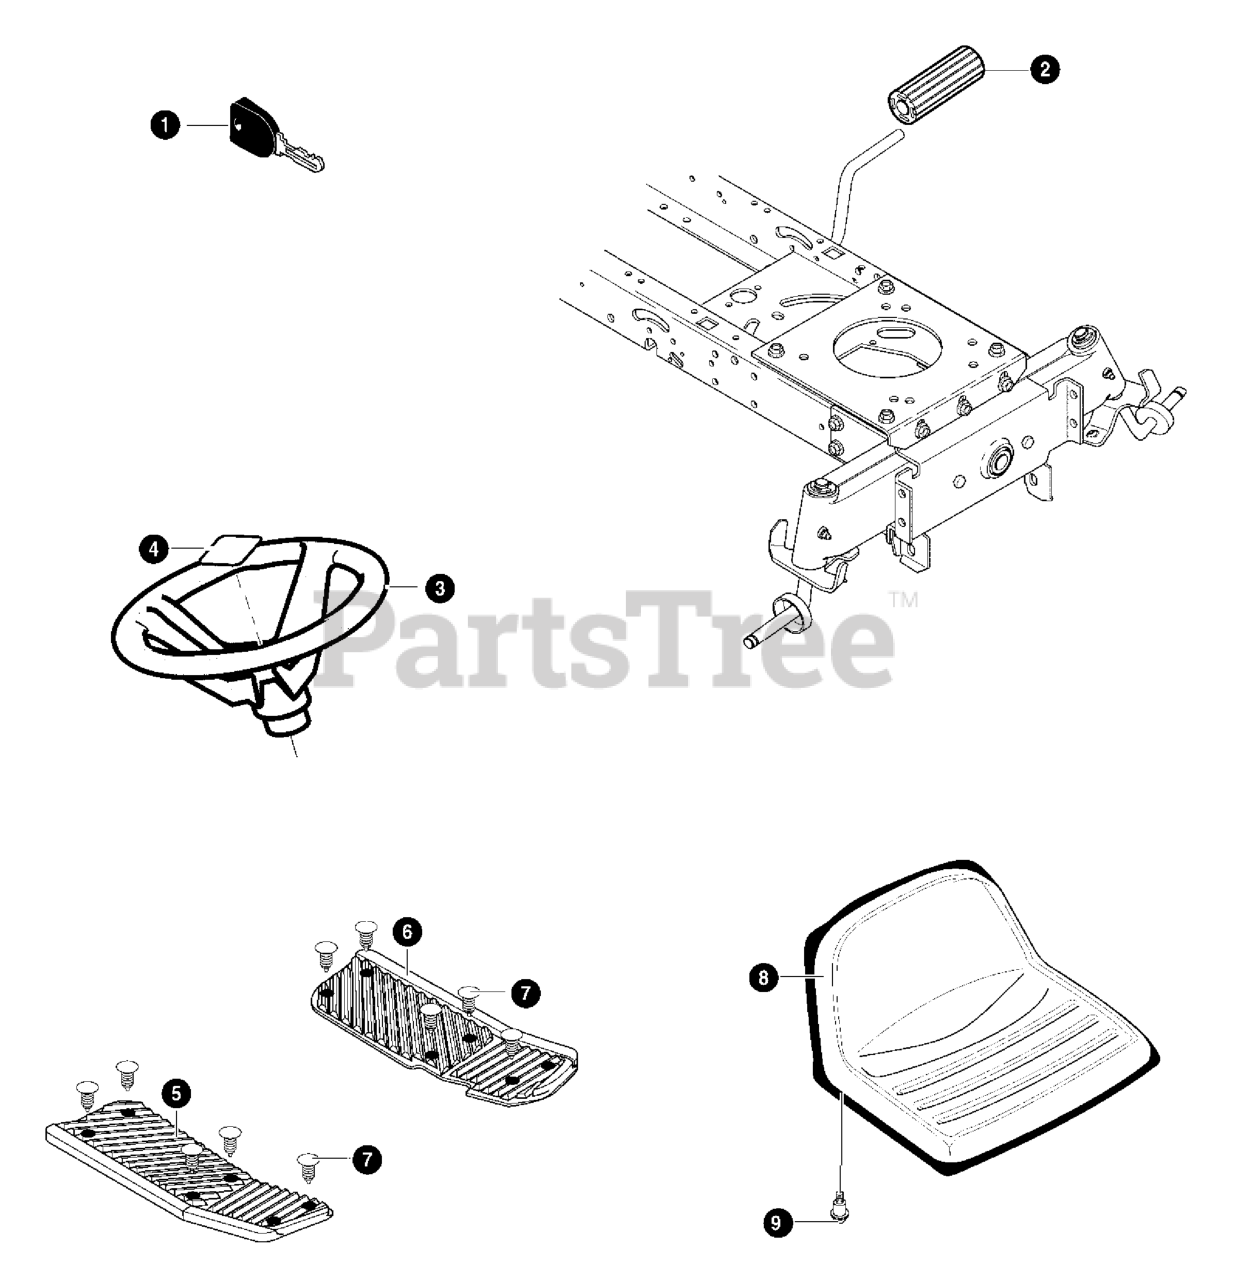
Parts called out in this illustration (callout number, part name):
1	KEY, IGNITION
2	COVER, PED, BRAKE
3	STEERING WHEEL
4	INSERT, 4-SPOKE
5	FOOTPAD, RH
6	FOOTPAD, LH
7	FASTENER RATCHET
8	SEAT, FAUL HI-BACK
9	BOLT, SHOULDER 5/16-18
